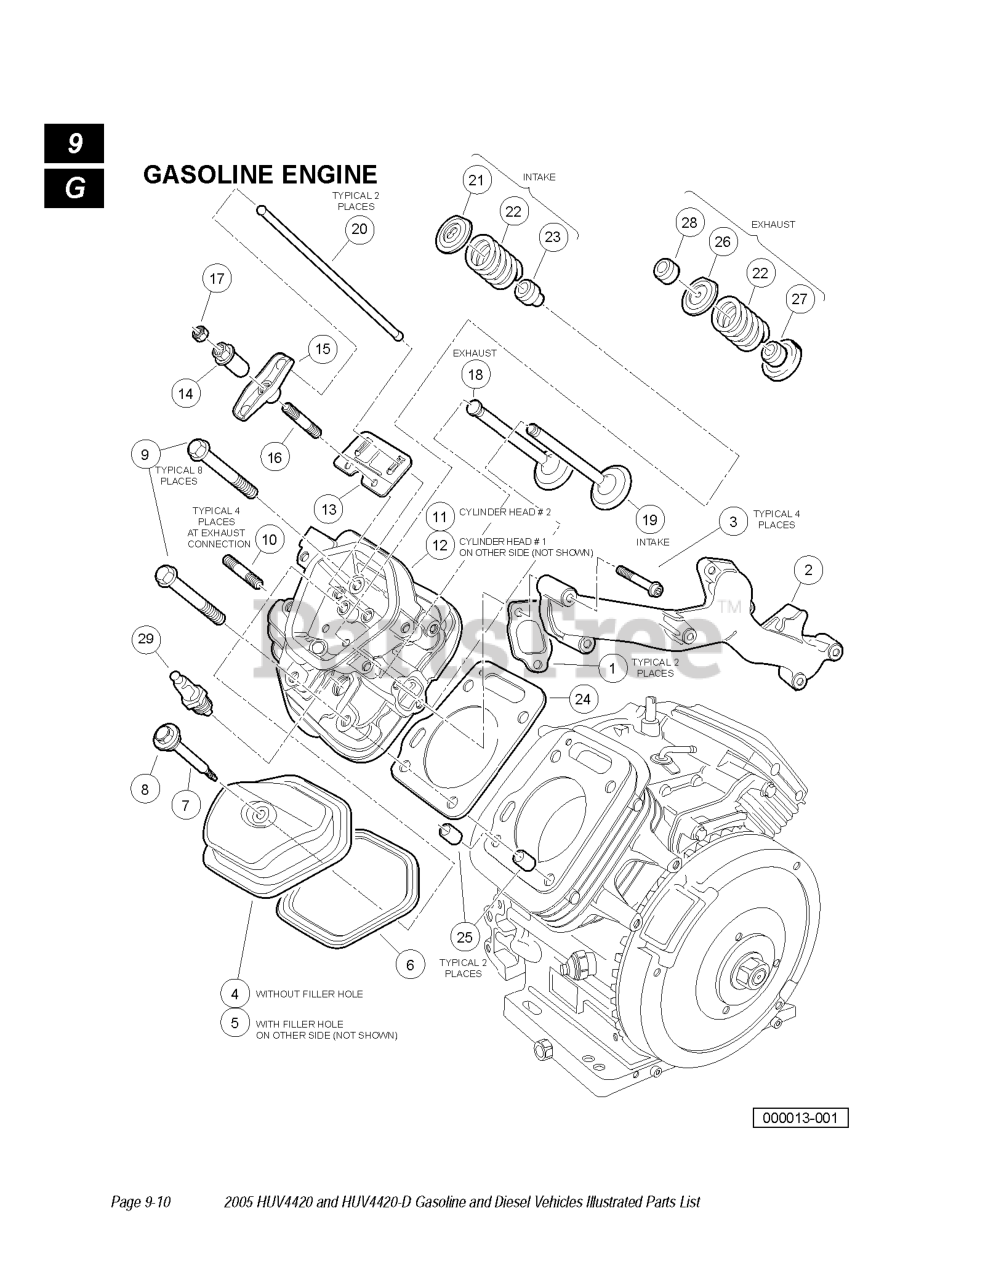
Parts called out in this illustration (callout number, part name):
1	GASKET, IN. MANIFOLD
2	MANIFOLD, IN
3	BOLT, SOCKET, M8 X 1.25 X 45
4	COVER, HEAD
5	COVER, HEAD FILLER
6	GASKET, CYLINDER HEAD COVER
7	BOLT, HEAD COVER
8	WASHER, HEAD COVER
9	BOLT, FLANGE, M10 X 1.5 X 80
10	BOLT, STUD, M8X22
11	CYLINDER HEAD, #2
12	CYLINDER HEAD, #1
13	PLATE, PUSH ROD GUIDE
14	PIVOT, ROCKER ARM
15	ARM, VALVE ROCKER
16	BOLT, PIVOT, M8
17	NUT, PIVOT ADJ
21	RETAINER, IN VALVE SPRING
22	SPRING, VALVE
23	SEAL, VALVE STEM
24	GASKET, CYLINDR HEAD
25	PIN A, DOWEL, 12 X 20
26	RETAINER, EX VALVE SPRING
27	SEAT, VALVE SPRING
28	ROTATOR, VALVE
29	Spark Plug, BPR2ES
